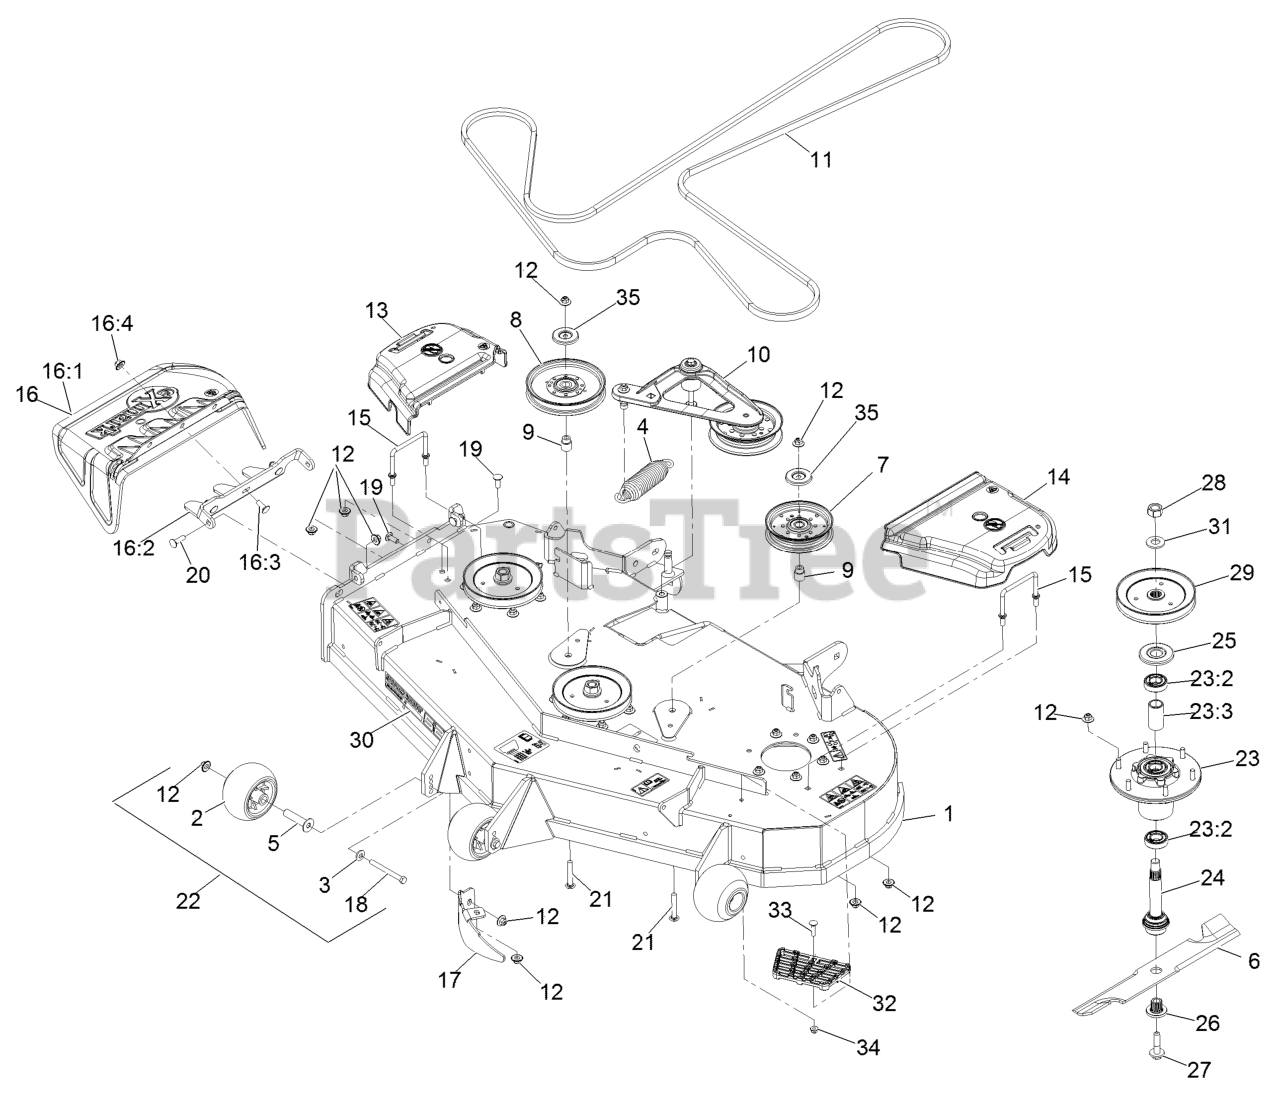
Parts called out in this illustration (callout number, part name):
1	ASM,Deck W/ Decals 52
2	Roller-Anti-Scalp
3	Washer-Spring Disc 3/8
4	Spring-Extension
5	Axle, Roller
6	Blade, Solid
6	Blade, Low Lift
6	Blade, Mulching
6	Blade-Notched
6	Blade-Extreme 2, 18.00"
7	Idler-Pulley, Flat 5.00X0.95
8	Idler-Pulley, Flat 6.00X0.75
9	Bushing, Idler
10	Deck Idler ASM
11	Belt,V-B X 186.00"
12	Nut-Nyloc 3/8-16 Flg
13	Cover-Belt, RH
14	Cover-Belt, LH
15	Wireform-Cover
16	ASM,Discharge Chute
16:1	Chute, Discharge
16:2	Bracket,Discharge Chute
16:3	Bolt-Carriage 3/8-16 X 1
16:4	Nut-Nyloc 3/8-16 Flg
17	Baffle-Dogleg, Lz-Vt52
18	Screw-HH 3/8-16 X 3 3/4 Gr 8
19	Bolt-Carriage 3/8-16 X 1
20	Bolt-Carriage 3/8-16 X 1 1/4
21	Bolt-Carriage 3/8-16 X 2 1/2
22	Kit, Anti-Scalp Roller
23	ASM-Cutter Hsg With Bearings
23:2	Bearing-Ball
23:3	Spacer-Bearing
24	ASM-Spindle And Seal
25	Guard,Bearing Top .989
26	Bushing, Splined
27	Screw-Sems 1/2-20 X 2.19
28	Nut-Hex
29	Sheave,Blade Drive 6.50
30	Decal, 524
31	Washer-Spring Disc 3/4
32	Step-Deck
33	Bolt-Carriage 5/16-18 X 1 1/4
34	Nut-Nyloc 5/16-18 Flg
35	Shield-Dust
